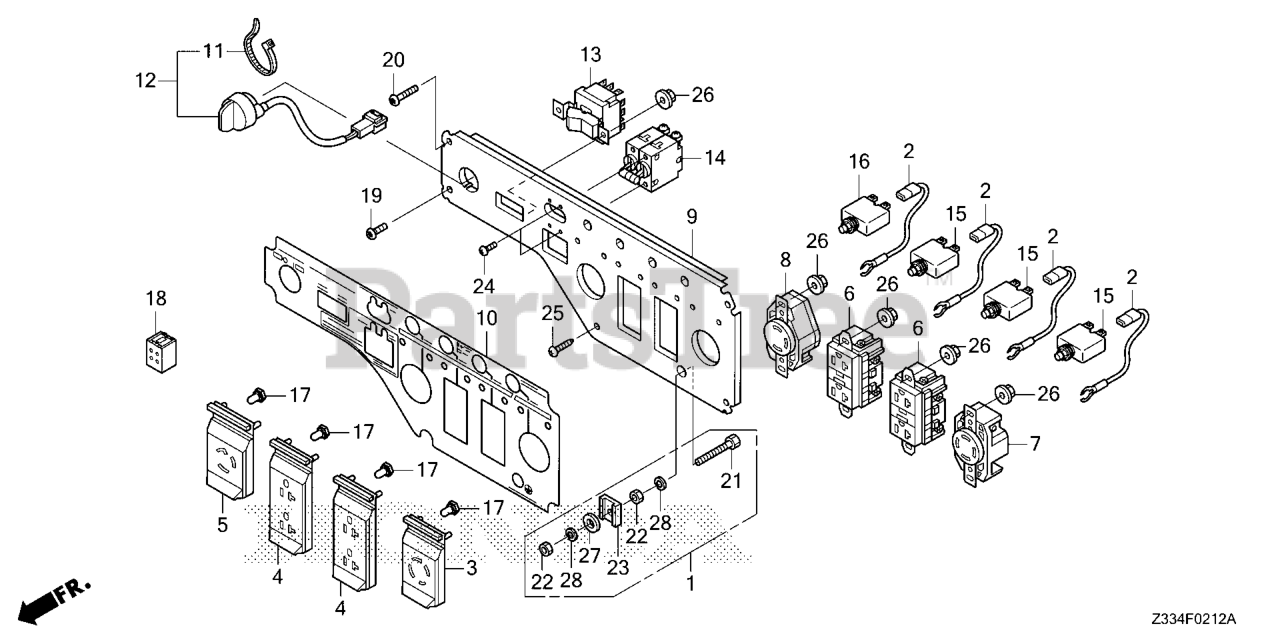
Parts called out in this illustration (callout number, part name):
1	TERMINAL SET, GROUND
2	SUB-WIRE ASSY.
3	COVER, RECEPTACLE (30A-125/250V)
4	COVER, RECEPTACLE (20A-125V)
5	COVER, RECEPTACLE (30A-125V)
6	RECEPTACLE (20A-125V) (GFCI)
7	RECEPTACLE (20A-125/250V)
8	RECEPTACLE (30A-125V)
9	PANEL, CONTROL *NH105* (AG) (MAT BLACK)
10	MARK, PANEL (CL-AG)
11	BAND
12	SWITCH ASSY., ENGINE STOP
13	SWITCH ASSY., VOLT CHANGE
14	BREAKER, CIRCUIT (17A)
15	PROTECTOR, CIRCUIT (20A)
16	PROTECTOR, CIRCUIT (30A)
17	COVER, CIRCUIT PROTECTOR
18	LED ASSY., INDICATER
19	SCREW, TRUSS (6X18) (TORX)
20	SCREW, TRUSS (6X30) (TORX)
21	BOLT, HEX. (6X28)
22	NUT, HEX. (6MM)
23	RETAINER (6MM)
24	SCREW, PAN (3X5)
25	SCREW, TAPPING (5X12) (PO)
26	NUT, FLANGE (4MM)
27	WASHER, PLAIN (6MM)
28	WASHER, SPRING (6MM)
